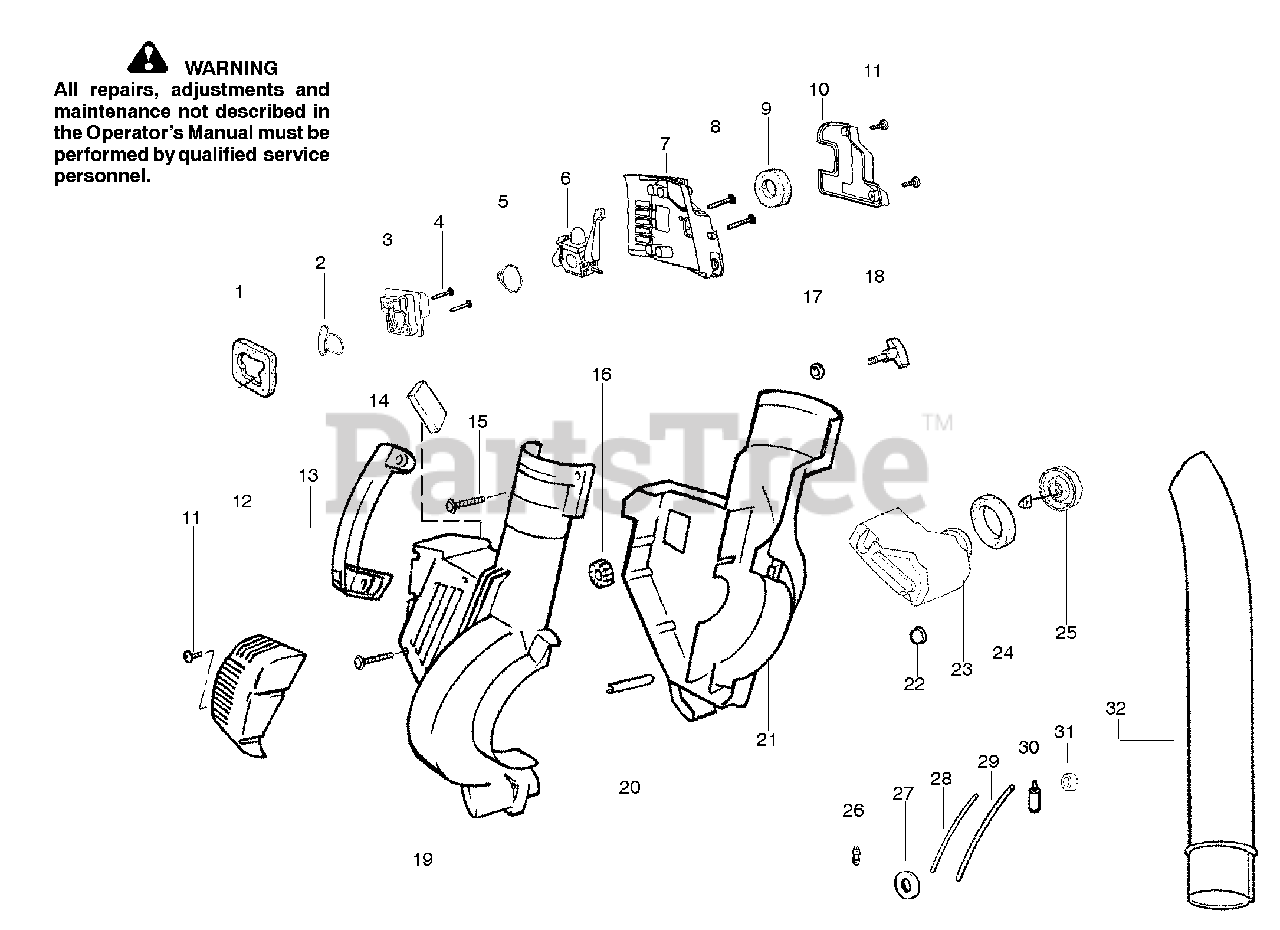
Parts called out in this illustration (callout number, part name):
1	Air Dam (kit)
2	Gasket-Adapter (kit)
3	Carburetor Adaptor
5	Gasket-Carburetor (kit)
6	Kit-Carb Ass'y. Zama-(C1Q-W11C)
6	Kit-Carb Ass'y. Walbro-(WT-606)
8	Screw-Carb.
9	Filter-Air
10	Cover-Air Filter
12	Guard-Muffler
14	Foam - 71.12mm (kit)
16	Isolator
18	Knob-Blower
19	Shroud-RH
20	Guide-Starter Rope
21	Shroud-LH
22	Isolator-Crankcase
23	Assy-Fuel Tank
24	Gasket-Fuel Tank
25	Fuel Cap w/Retainer
26	Fitting-Fuel Line
27	Grommet-Shroud
28	Kit-Line Carb/Purge
29	Kit-Line Tank/Purge
30	Assy-Fuel Pick-up
31	Grommet-Fuel line (kit)
32	Tube-Blower
